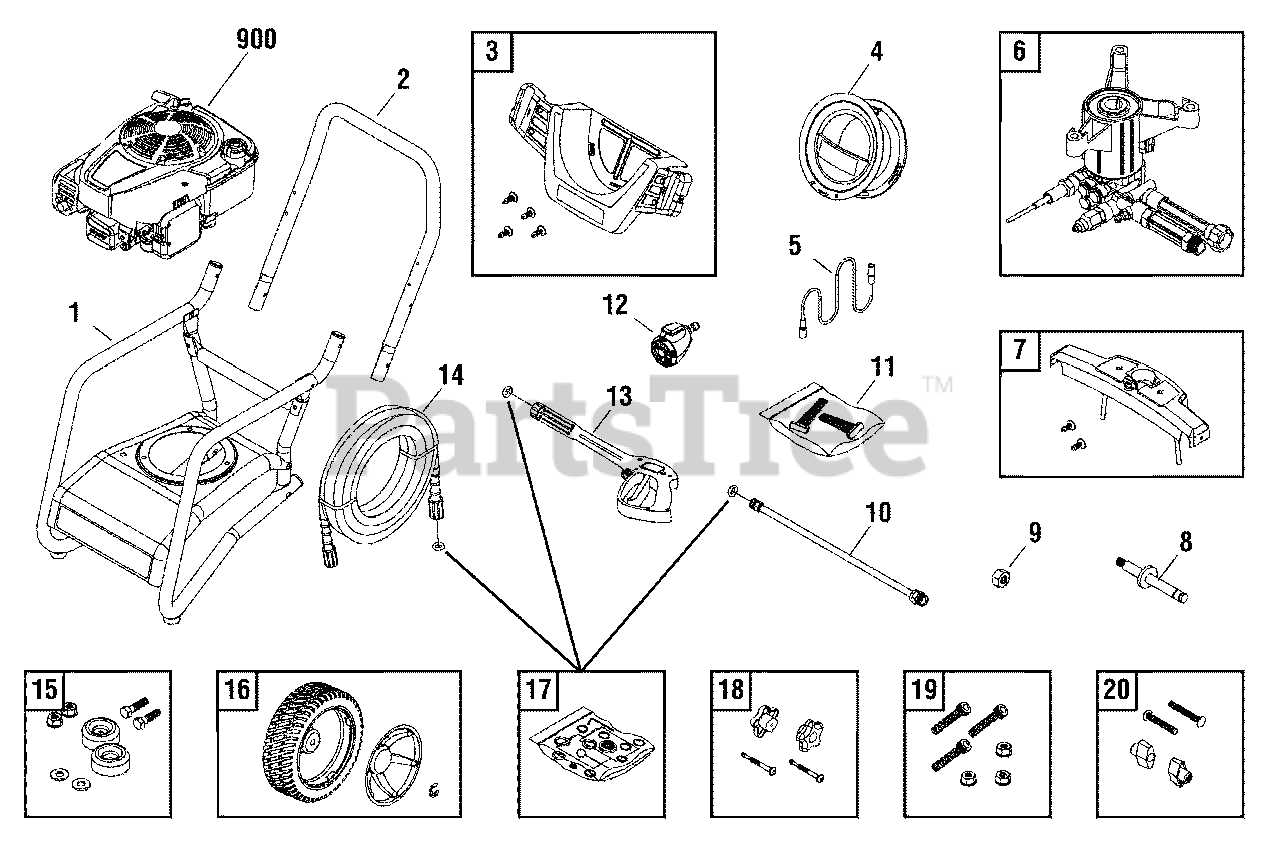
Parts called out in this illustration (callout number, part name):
1	BASE
6	PUMP
9	NUT
10	EXTENSION, QC
13	GUN
15	MOUNT, Vibration
17	KIT, O-Ring
19	KIT, Hardware, Pump Mounting
